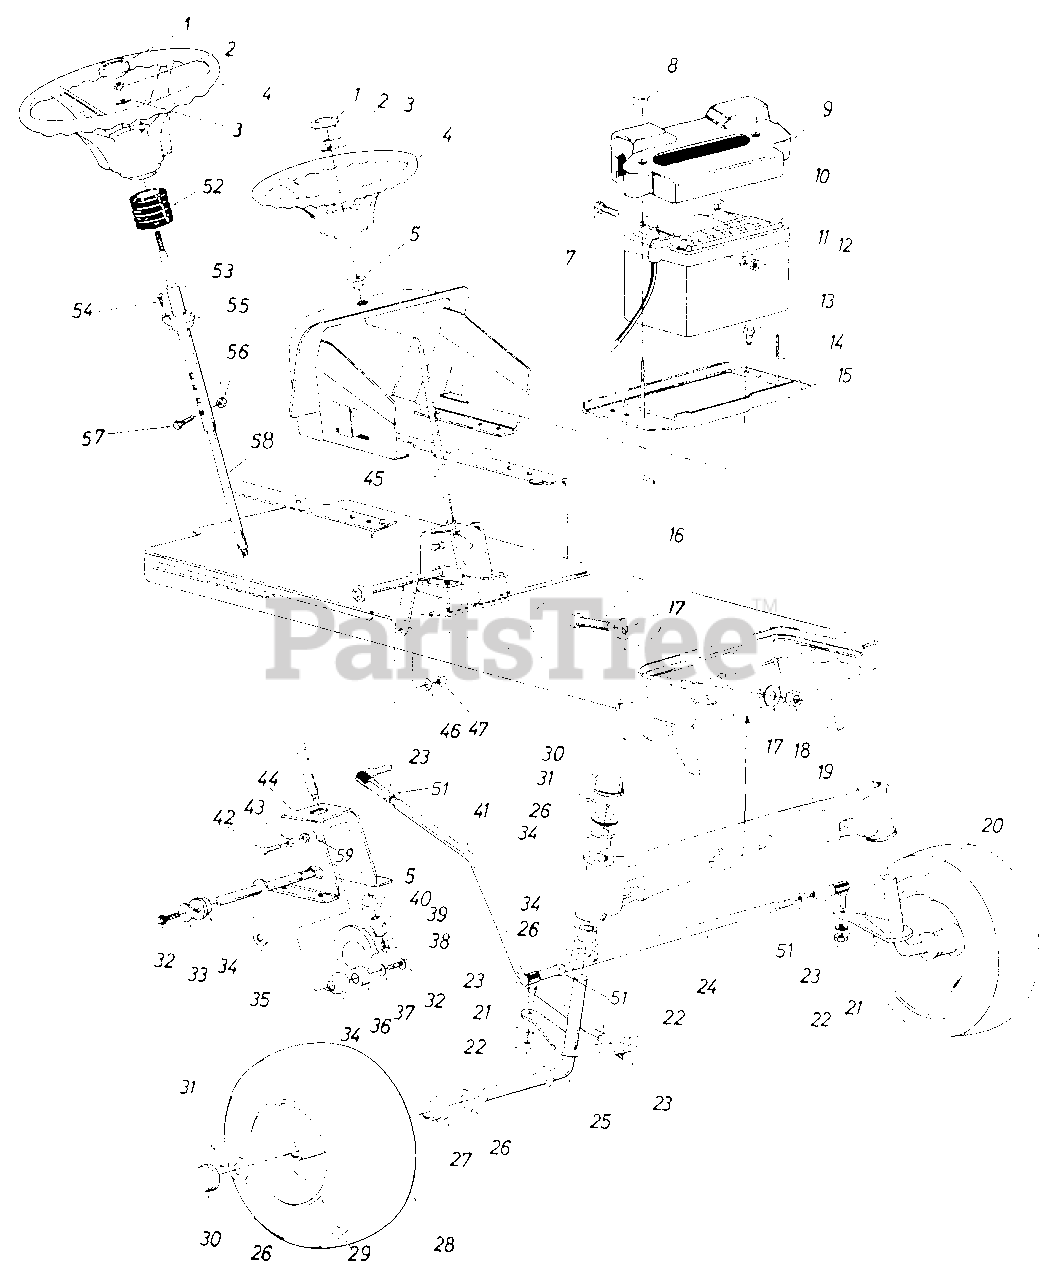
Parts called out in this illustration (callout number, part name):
1	Steering Wheel Cap
2	Hex Cent. L-Nut 5/16-24 Thd.
3	Bell-Wash. 5116" I.D. x .87" O.D. x .C60
4	Steering Wheel
5	Plastic Hex Bearing 5/8" I.D.
7	Hex Scr. 1/4-20 x .62" Lg.
8	Wing Nut Plastic 1/4-20 Thd.
9	Battery Cover
10	12-V Battery
11	L-Wash 1/4" I . D .
12	Hex Nut 1/4-20 Thd.*
13	Hex Thd. Rolling Scr. 1/4-20 x.50" Lg.
14	Battery Hold Down Rod
15	Battery Plate
16	Hex Scr. 5/8-18 x 2.50" Lg.
17	Flat Wash. .66" I.D. x 2.25" O.D. x .17
18	Hex Cent. L-Nut 5/8-18 Thd.
19	Front Pivot Bar Ass'y.
20	Front Axle Ass'y.-L.H.
21	L-Wash. 3/8" Scr.
22	Hex Nut 3/8-24 Thd.
23	Ball Joint Ass'y.
24	Tie Rod
25	Front Axle Ass'y.-R.H.
26	Fl-Wash. .780 I.D. x 1.59 O.D.
27	Flange Bearing
28	Front Wheel Ass'y. Comp.
29	Front Wheel Rim Only
30	Dust Cover
31	Cotter Pin 5132" Dia. x 1.00"
32	Hex Scr. 3/8-24 x .75" Lg. Grade 5
33	Fl-Wash. 3/8 I.D. x 1.25 O.D. x .090
34	Flange Double "D" Brg. .753 I .D.
35	Steering Arm Shaft Ass'y.
36	Side Gear-Steering
37	Bell-Wash. 3/8" I.D.
38	Hex Cent. L-Nut 5/16-24 Thd.
39	Fl-Wash. 5116" I.D. x .62 O.D. x .059
40	Pinion Gear-Steering
41	Drag Link
42	Hex Cap Scr. 3/8-16 x 1.25" Lg.
43	Hex Nut 3/8-16 Thd.*
44	Steering Gear Sup. Ass'y.
45	Steering Shaft
46	L-Wash. 3/8" I.D.*
47	Hex Nut 3/8-24 Thd.*
51	Hex Jam Nut 3/8-24 Thd.
52	Steering Bellow
53	Upper Steering Shaft
54	Oval Hd. Cr.-Sunk Scr. #10 x 518" Lg.
55	Fl-Bearing .89" I.D. x 1.36" O.D.
56	Hex L-Nut 1/4-20 Thd.
57	Hex Bolt 1/4-20 x 1.31" L9.
58	Lower Steering Shaft
59	Nylon Cap
